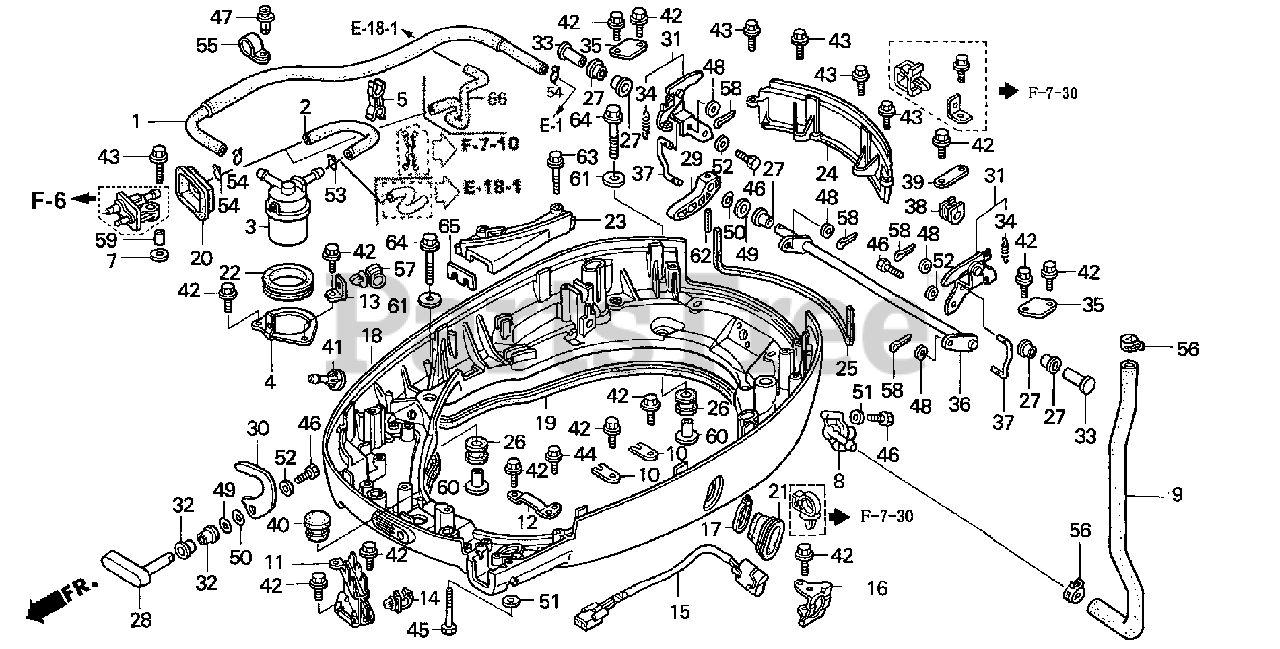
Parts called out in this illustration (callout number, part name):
1	TUBE, FUEL
2	TUBE B, FUEL
3	FILTER, FUEL
4	STAY, FUEL STRAINER
5	CLAMP C, BREATHER TUBE
7	WASHER, PIVOT
8	JOINT, WATER INLET
9	HOSE, FLUSHING WATER
10	PLATE, SHIFT SHAFT
11	BRACKET, CONNECTOR (B)
12	BRACKET, CABLE CLIP (S)
13	BRACKET, CLIP (C)
14	CLAMP, WIRE
15	SWITCH ASSY., POWER TRIM-TILT
16	STAY, POWER TILT SWITCH
17	BAND (BLACK 3.5X140)
18	CASE, ENGINE (LOWER) *NH282MU* (OYSTER SILVER METALLIC-U)
19	SEAL, CASE (LOWER)
20	GROMMET, CASE (LOWER) (B)
21	GROMMET, CASE (LOWER) (G)
22	GROMMET, FUEL STRAINER
23	CASE, SEPARATE *NH282MU* (OYSTER SILVER METALLIC-U)
24	CASE, RR. SEPARATOR *NH282MU* (OYSTER SILVER METALLIC-U)
25	SEAL, SEPARATOR CASE
26	RUBBER, FR. CARRIER CUSHION
27	BUSH (14X10)
28	LEVER, COVER LOCK *NH282MU* (OYSTER SILVER METALLIC-U)
29	LEVER, COVER LOCK
30	HOOK, COVER LOCK
31	HOOK, COVER LOCK
32	BUSH, COVER LOCK
33	SHAFT, COVER B LOCK
34	SPRING, COVER LOCK HOOK
35	PLATE, COVER LOCK SHAFT
36	SHAFT, COVER LOCK
37	ROD, COVER LOCK
38	BUSH, COVER LOCK SHAFT
39	PLATE, COVER B LOCK SHAFT
40	CAP, L. SIDE COVER
41	GROMMET, WATER CHECK
42	BOLT, FLANGE (6X12)
43	BOLT, FLANGE (6X20)
44	BOLT, FLANGE (5X10)
45	BOLT, HEX. (6X40)
46	BOLT, HEX. (6X16)
47	SCREW, RIVET (5X10)
48	WASHER, PLAIN (5MM)
49	WASHER (14MM)
50	WASHER, WAVE (14MM)
51	WASHER, PLAIN (6MM)
52	WASHER (6MM)
53	CLIP, TUBE (B10)
54	CLIP, TUBE (B12)
55	CLIP (14MM)
56	CLAMP, TUBE (D18.8)
57	CLIP, HARNESS
58	PIN, SPLIT (2.0)
59	COLLAR, DISTANCE (6MM)
60	COLLAR (8.3X14.5)
60	COLLAR (8.5X14.5)
61	WASHER, PLAIN (8MM)
62	PIN, SPRING (6X22)
63	BOLT, FLANGE (6X30)
64	BOLT, FLANGE (8X35)
65	PLATE, REMOTE CONTROL CABLE
